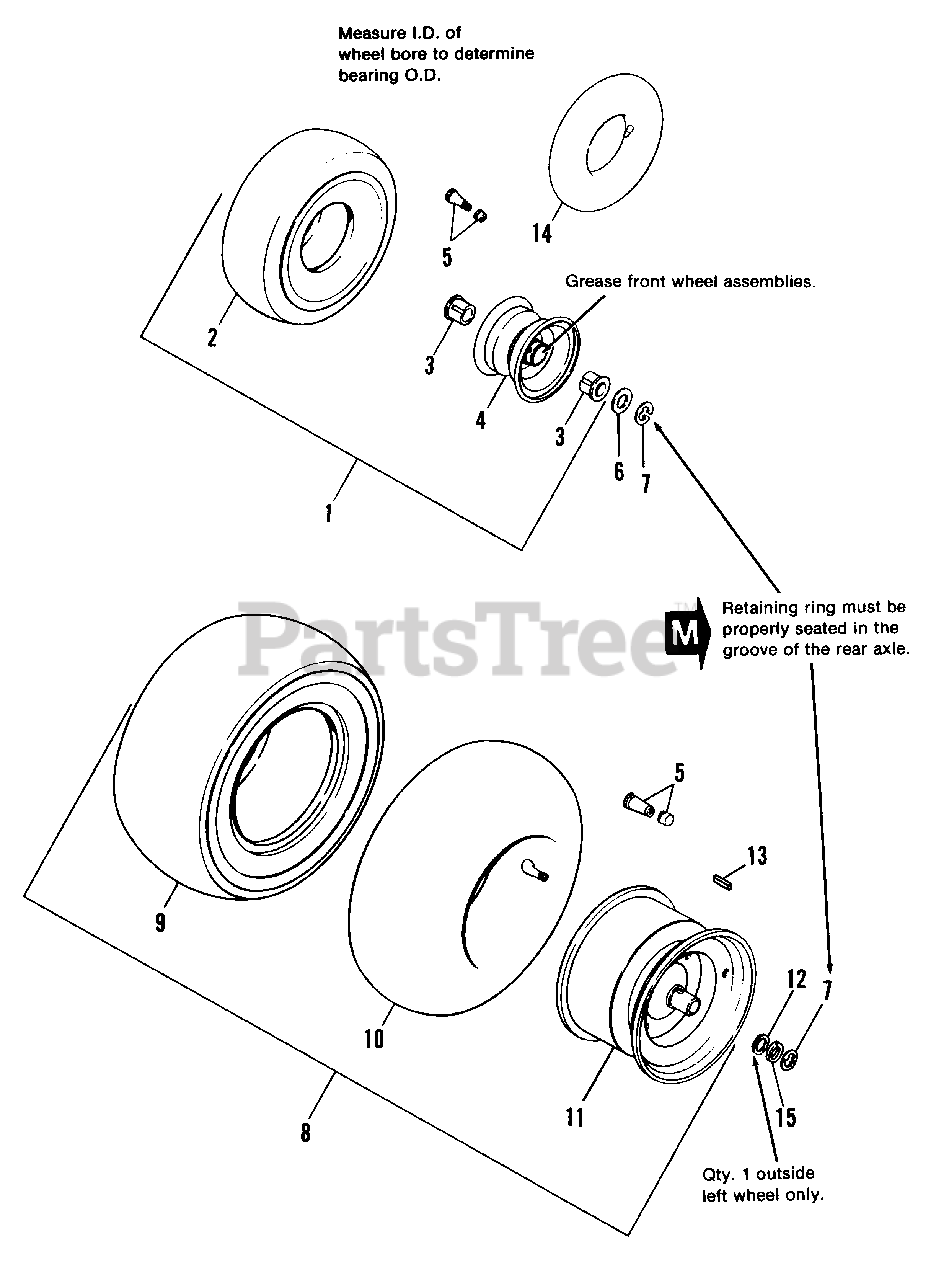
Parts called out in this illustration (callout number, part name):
1	FRONT WHEEL & TIRE ASSY.
2	TIRE, Turf, 4.10/3.50-4 (Carlisle)
3	BEARING, Flange Wheel (O.D. 1-1/8)
3	BEARING, Flange Wheel (O.D. 1-3/8)
4	WHEEL ASSY. (Incl. Ref. No. 3)
5	VALVE STEM & CAP
7	E-RING, Retaining, 3/4
8	REAR WHEEL & TIRE ASSY.
9	TlRE,Tubeless, 16 x 6.50-8 (Carlisle)
10	TUBE, (See note below) (Rear Wheels)
11	WHEEL ASSY.
12	WASHER, Plain
13	KEY, 3/16 x 3/16 x 1-1/2
14	TUBE, (See note below) (Front Wheels)
15	WASHER, 3/4 x 1-39/64 x 1/2
